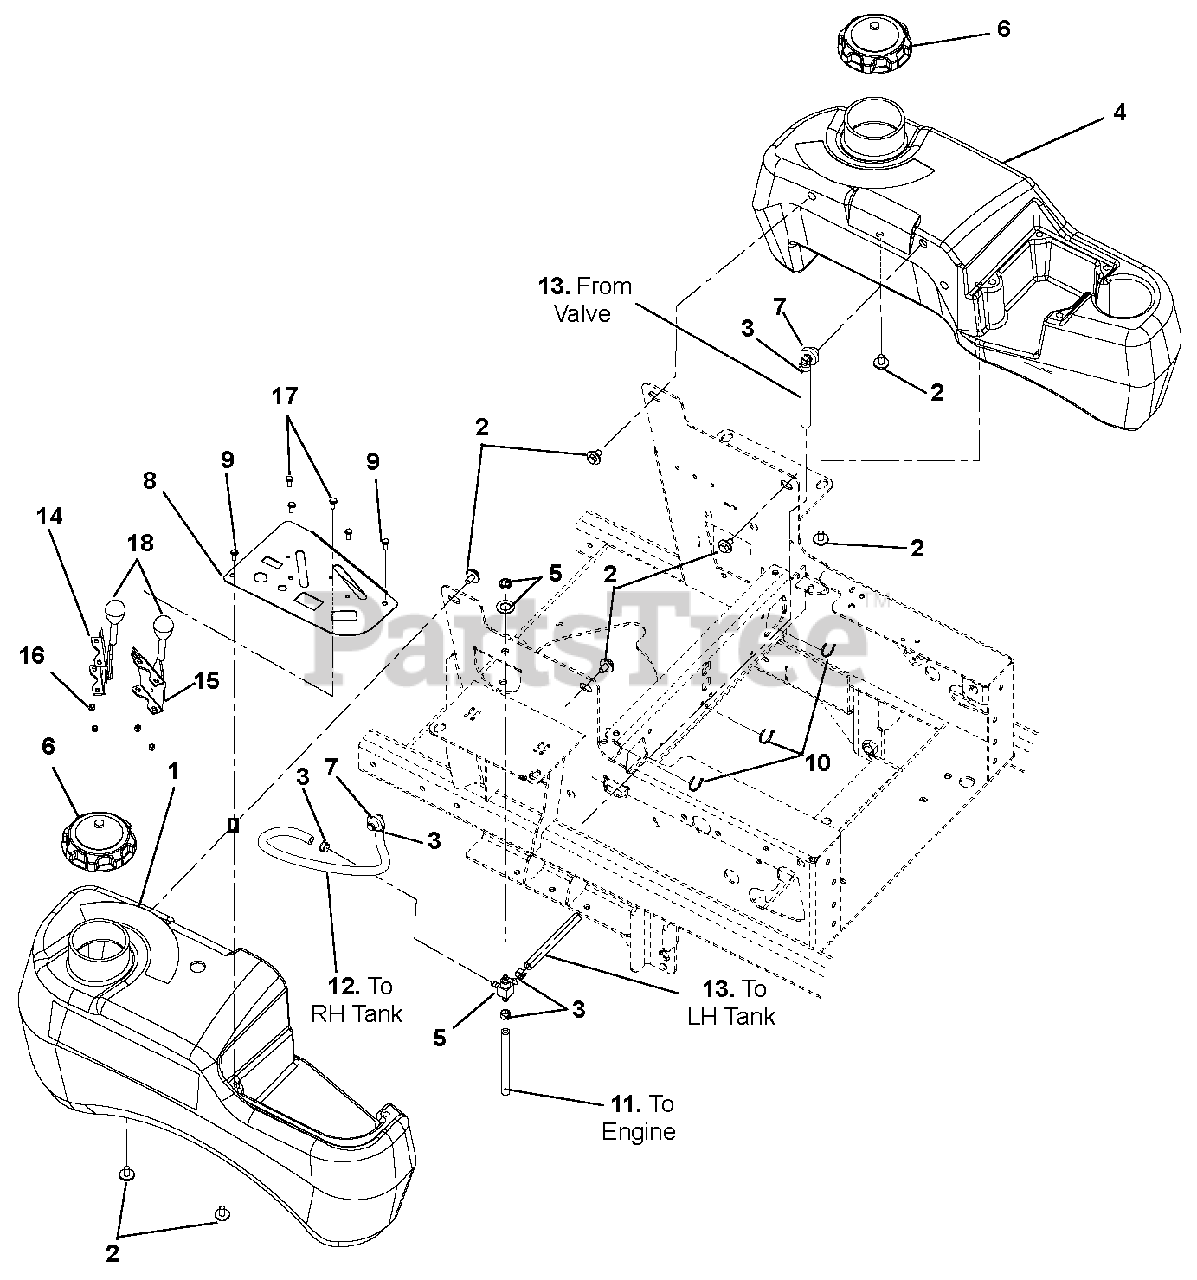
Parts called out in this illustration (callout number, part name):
1	Tank, Right Hand Fuel
2	Bolt, SEMS .31-18 x .62
3	Clamp, Fuel Line
4	Tank, Left Hand Fuel
5	Valve, Fuel
6	Cap, Fuel
7	Assembly, Medium Tank Fuel Pick-up
8	Panel, Control
9	Screw, Machine 10-24 x .50
10	Cable, Tie
11	Hose, .25 Low-PERM Bulk Gas
12	Hose, .25 Low-PERM Bulk Gas
13	Hose, .25 Low-PERM Bulk Gas
14	Cable, Pro-Turn 100 Choke Control
15	Cable, Pro-Turn Throttle Control
16	Nut, Locking Nylon 10-24 with Insert
17	Screw, Machine 10-24 x .50 Hex Washer Head
18	Knob, Control, Black .38-16 x .62
